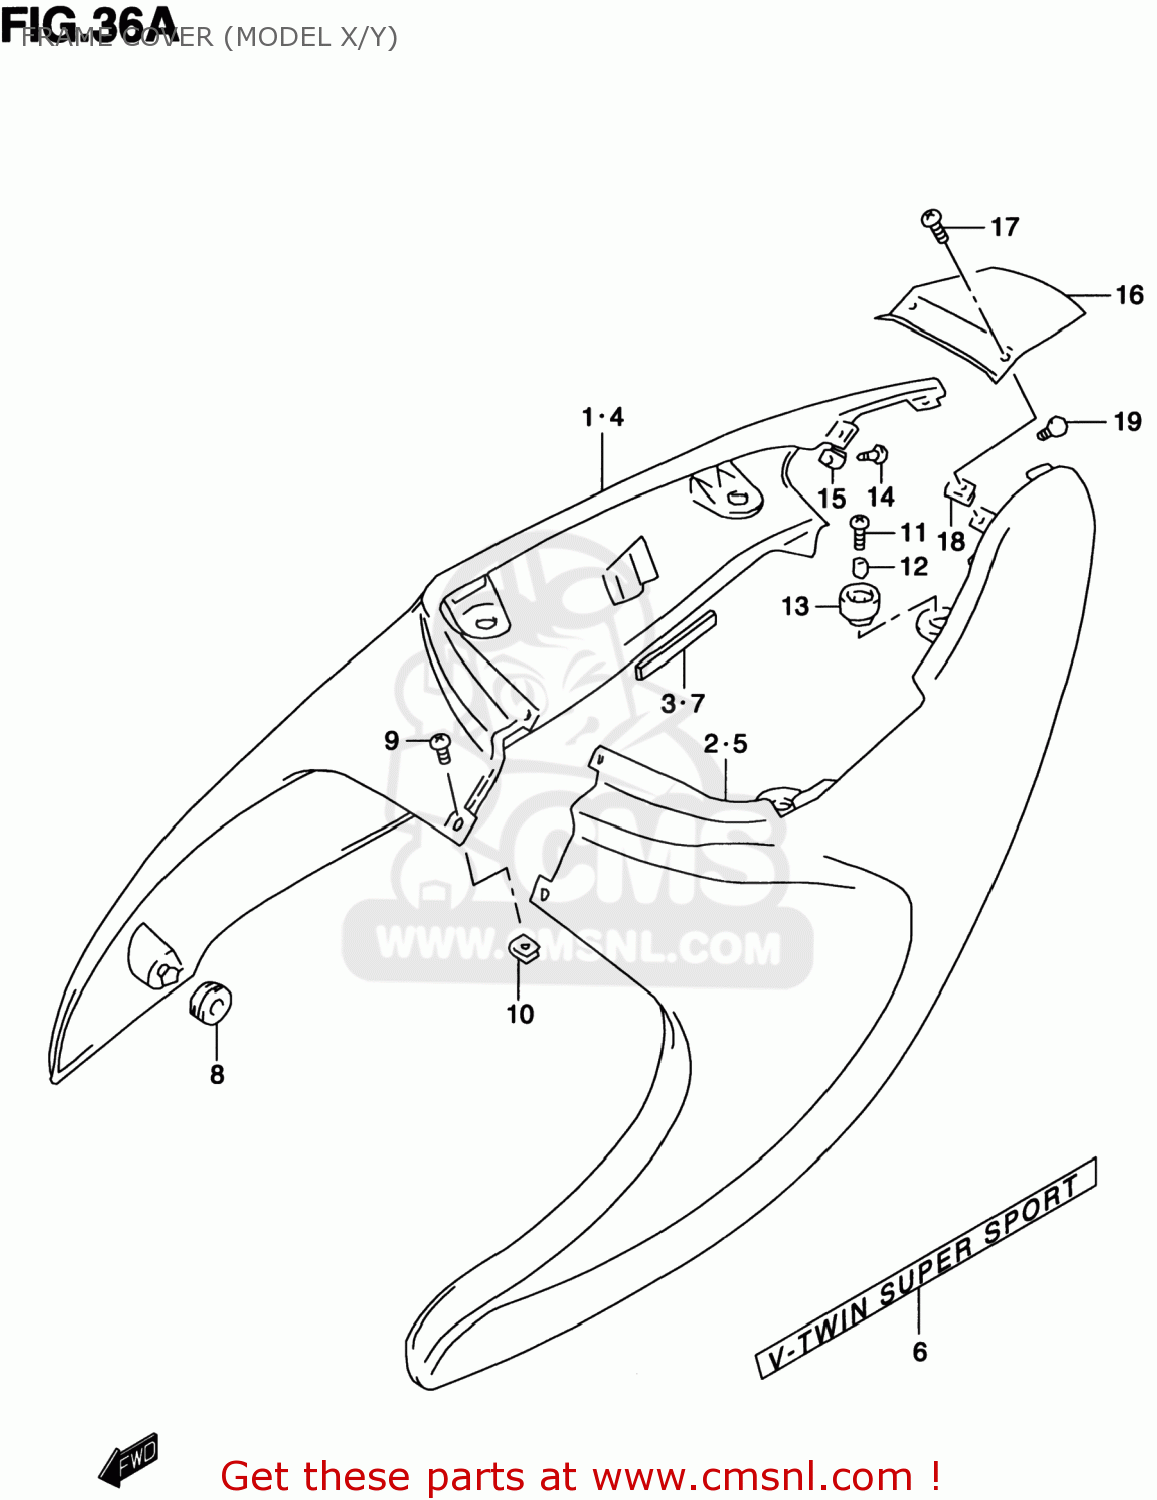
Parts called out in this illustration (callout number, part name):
1	COVER,FRAME,R(RED)
2	COVER,FRAME,L(RED)
3	CUSHION,FRAME COVER
4	COVER,FRAME,R(BLUE)
5	COVER,FRAME,L(BLUE)
6	EMBLEM,COVER
7	CUSHION,FRAME COVER
8	CUSHION
9	SCREW
10	NUT
11	SCREW(6X20)
12	SPACER(6.5X10X9.4)
13	CUSHION
14	SCREW(5X16)
15	NUT
16	COVER,FRAME CTR
17	SCREW
18	NUT
19	CUSHION
